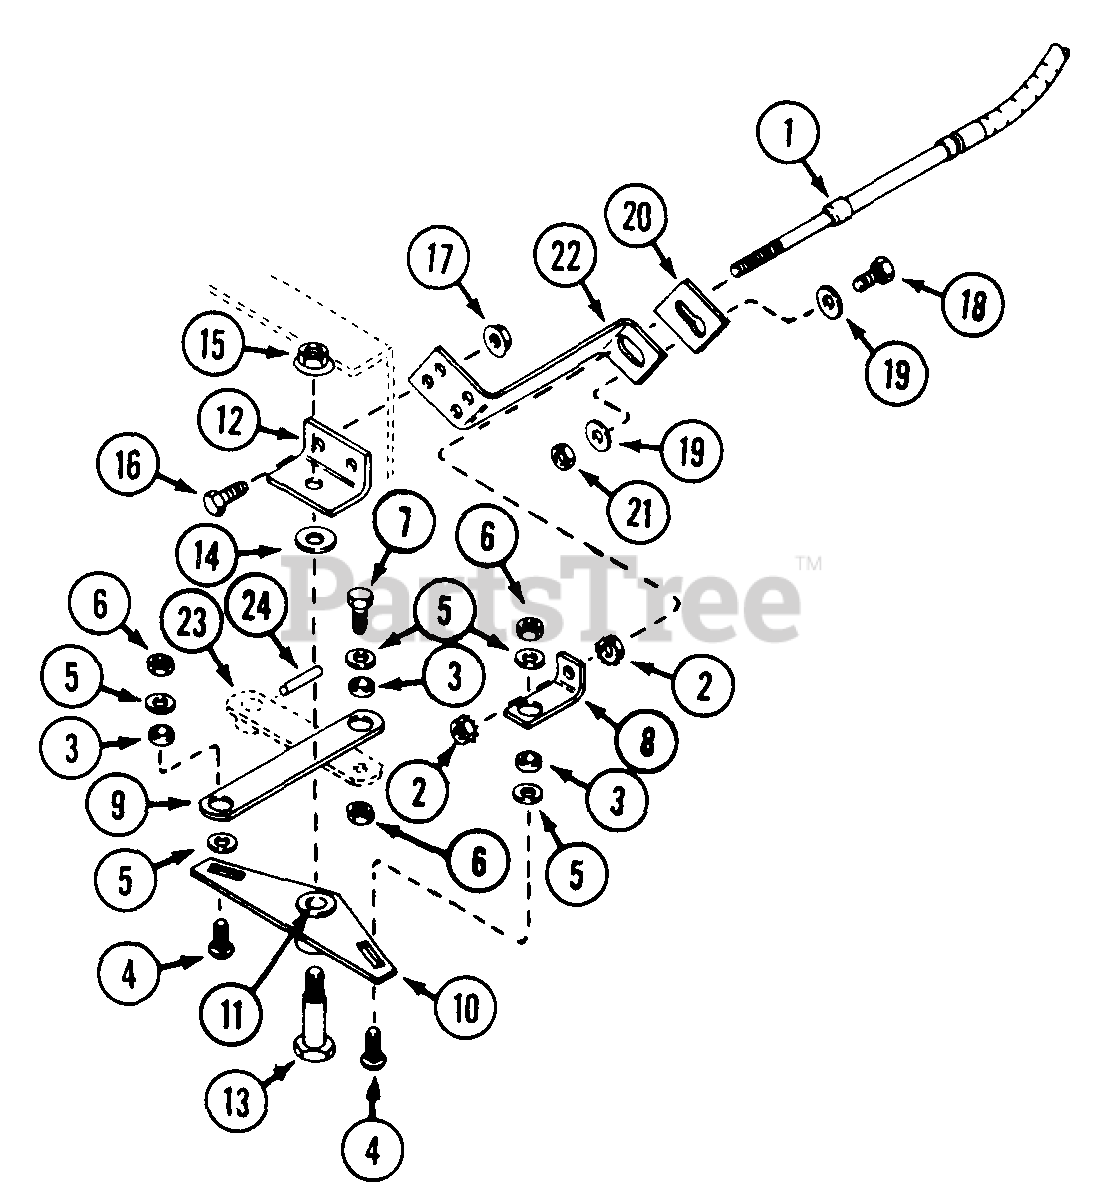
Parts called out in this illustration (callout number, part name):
1	CABLE - steering 46"
3	BUSHING - steering cable
4	BOLT - 1/4"-20 x 1" carriage
5	WASHER - 1/4"
6	NUT - 1/4"-10
7	BOLT - 1/4"-20 x 1"
8	BRACKET - steering cable end
9	LINK - control cable
12	BRACKET - bellcrank mounting
13	BOLT - shoulder
14	WASHER - 1/2"
15	NUT - 3/8"-16 flange lock
16	BOLT - 5/16"-18 x 1"
17	NUT - 5/16"-18
18	BOLT - 1/4"-20 x 1"
19	WASHER - 1/4"
20	PLATE - cable mounting
21	NUT - 1/4"-20 lock
22	BRACKET - cable mounting
23	ARM - transmission
